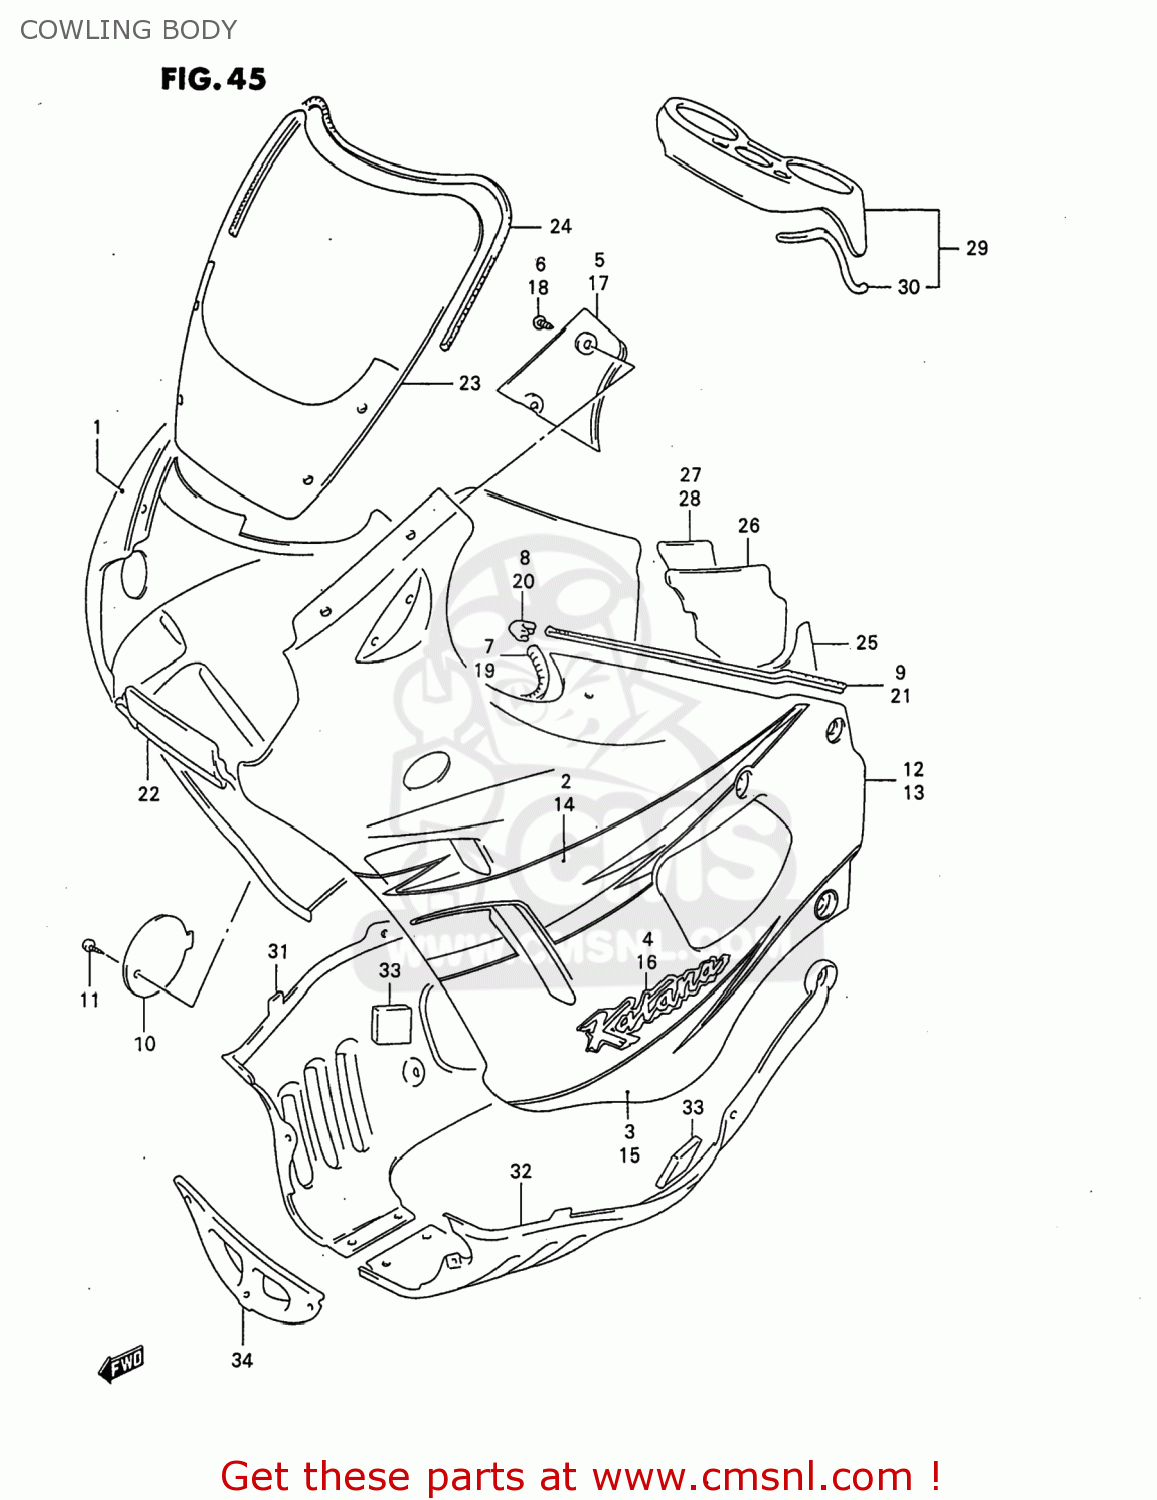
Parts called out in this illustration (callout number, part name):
1	COVER ASSY,COWLING,R
2	TAPE,BODY COWL SIDE UPR,R
3	TAPE,BODY COWL SIDE LWR,R
4	EMBLEM,BODY COWLING SIDE
5	COVER,METER SIDE,RIGHT
6	SCREW
7	MOLD,COWLING
8	JOINT,MOLDING END
9	MOLDING
10	LID,OIL
11	SCREW(6X16)
12	COVER ASSY,COWLING,L
13	COVER ASSEMBLY,COWLING,LEFT
14	TAPE,BODY COWL SIDE UPR,L
15	TAPE,BODY COWL SIDE LWR,L
16	EMBLEM,BODY COWLING SIDE
17	COVER,METER SIDE,LEFT
18	SCREW
19	MOLD,COWLING
20	JOINT,MOLDING END
21	MOLDING
22	PANEL,COWLING CTR
23	WINDSCREEN
24	MOLDING,WINDSCREEN
25	SHEET,COWLING BALANCER
26	BALANCER SHEET,COWLING,R
27	CUSHION,COWLING,R
28	CUSHION,COWLING,L
29	COVER,METER
30	MOLDING,METER COVER
31	COVER,COWLING UNDER,R
32	COVER,COWLING UNDER,L
33	CUSHION,UNDER COWLING
34	COVER,COWLING UNDER FR
